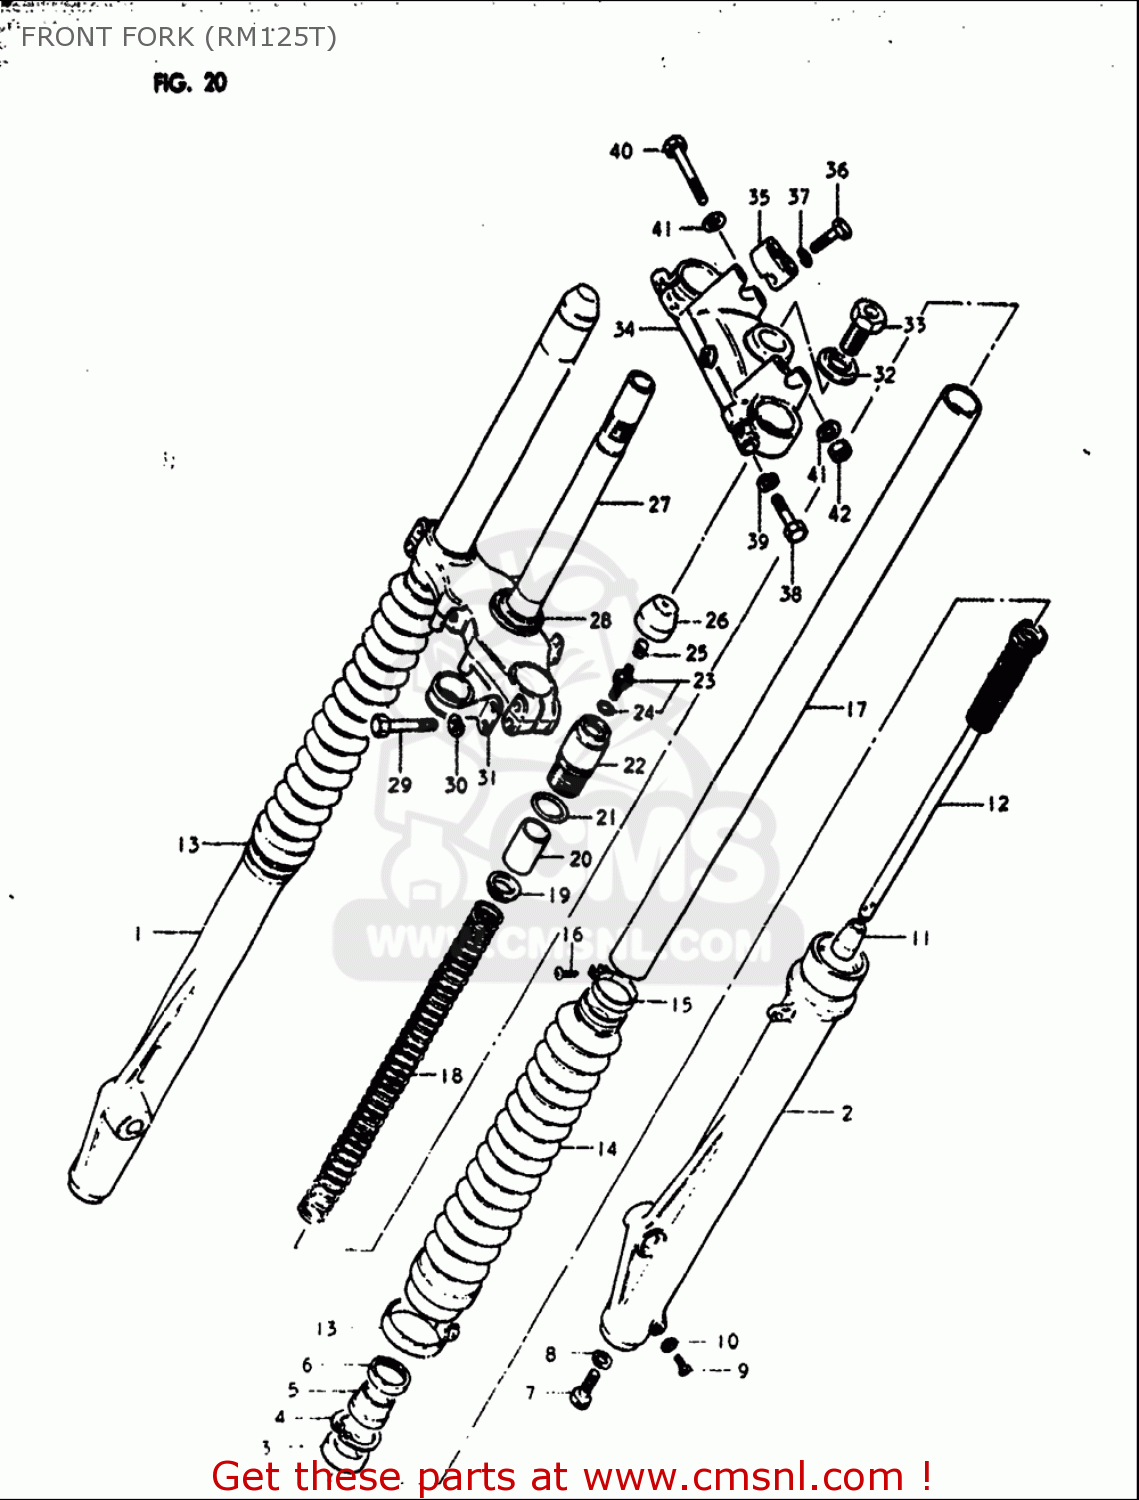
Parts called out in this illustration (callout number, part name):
3	SEAL,OIL
4	RING,STOPPER
5	SEAL,DUST
6	CASE,DUST SEAL
7	BOLT,CYLINDER
8	GASKET,CYLINDER (NAS)
9	SCREW
10	GASKET,DRAIN,PLUG (NAS)
14	BOOT
15	BAND,BOOT
16	SCREW
19	GUIDE
21	O RING
23	VALVE
24	O RING
25	CAP,VALVE AIR
26	CAP
29	BOLT
30	WASHER,LOCK
31	CLIP,CABLE
32	WASHER
33	BOLT
35	HOLDER,HANDLEBAR
36	BOLT
37	WASHER,LOCK
38	BOLT
39	WASHER,LOCK
40	BOLT
41	WASHER
42	NUT
